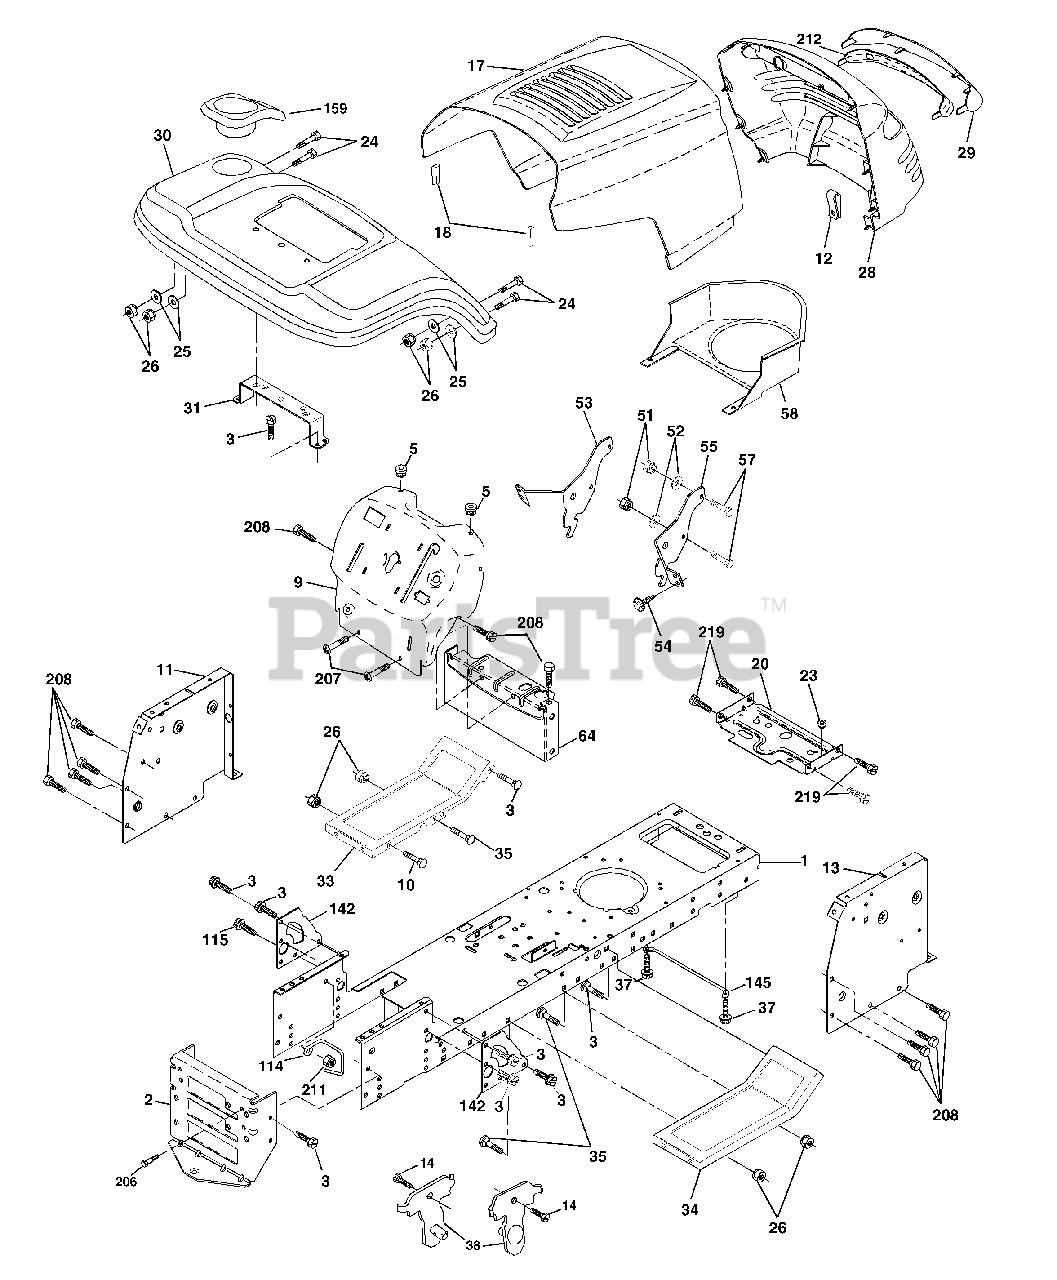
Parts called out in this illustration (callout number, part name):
1	Chassis
2	Drawbar
3	Screw 3/8-16x.75
5	Bumper Hood/Dash
9	Dash P/L
10	Bolt Carriage 3/8-16 x 1
11	Panel Dash Lh
12	Clip Tinnerman
13	Panel Dash Rh
14	Screw Thdrol 3/8-16 x 1-1/4
17	Hood LT/PL
18	Bumper Hood
20	Plate Mtg Battery Fuel Tank Fr
23	Bushing
24	Bolt Fin Hex 3/8-16 x 1 Gr 5
25	Washer 13/32 X 13/16 X 12 Ga
26	Nut Lock Hex W/Ins 3/8-16 Unc
28	Grille LT/PL
29	Lens LT/PL
30	Fender Footrest STLT Pnt
31	Bracket Support Fender
33	Footrest Pnt Lh
34	Footrest Pnt Rh
35	Bolt Rdhd Sht Sqnk 3/8-16 x 3/4
37	Screw Thdrol 6/16-18 x 1/2 TYT
38	Bracket Asm. Pivot Mower Rear
51	Nut Lock Hex W/Ins 1/4-20
52	Washer 9/32 x 7/8 x 16 Ga.
53	Bracjet Grukke Lh
54	Screw Hex Wshd 8-18 x 7/8
55	Bracket Grille Rh
57	Bolt Hex 1/4-20 x 3/4
58	Duct Air
64	Dash Lower STLT
114	Keeper Belt Rear Lh
115	Screw 3/8-16 x 1-1/4
142	Plate Reinforcement STLT
145	Rod Pivot Chassis/Hood
159	Cupholder
206	Bolt Shoulder 5/16-18
207	Screw Thdrol 5/16-18 x 1/2
208	Screw Thdrol 3/8-16 x 1/2
211	Nut Hex Flange Lock
212	Insert Lens Reflect P/L LT
219	Screw 5/16-18 x 3/4
